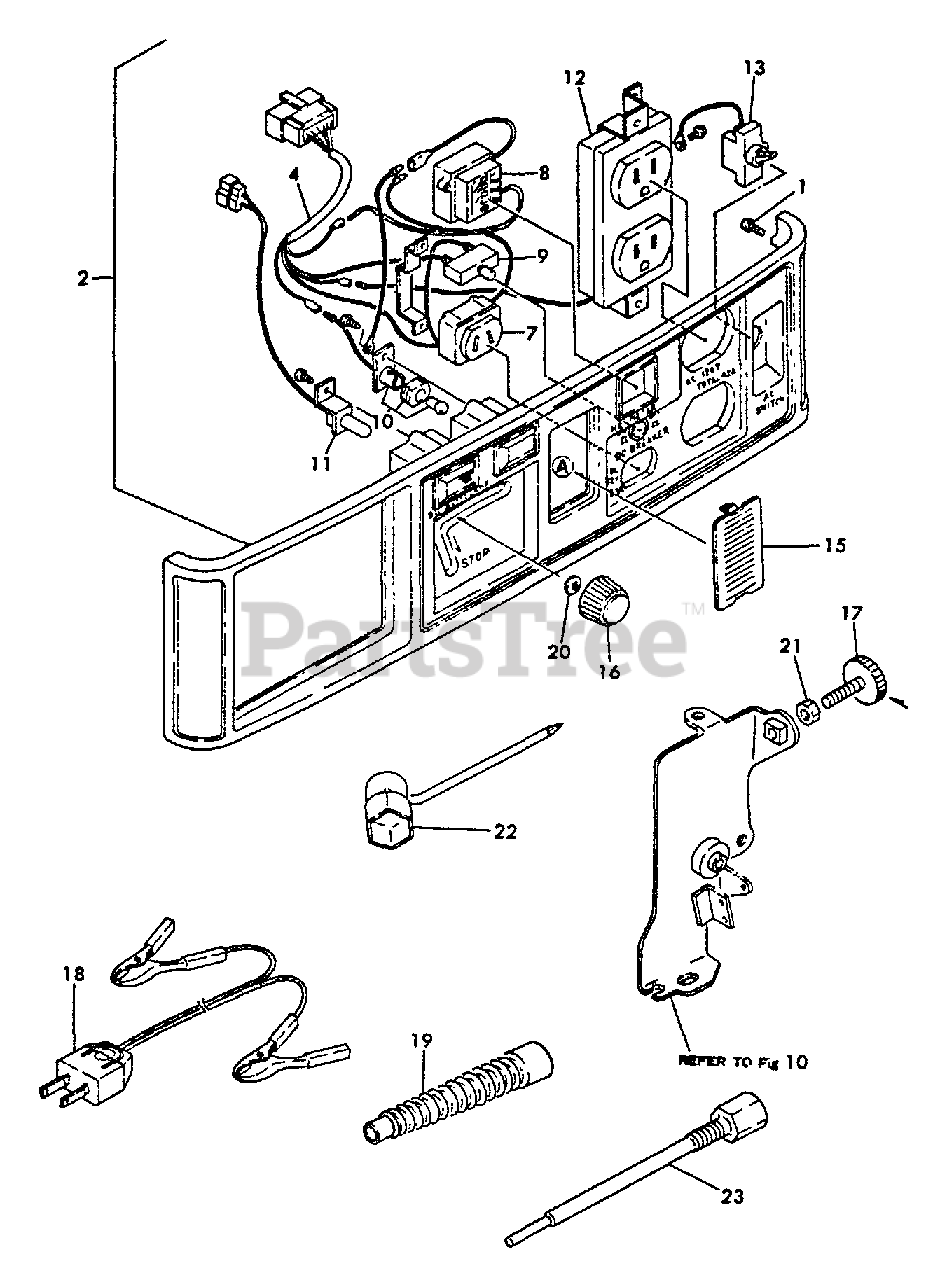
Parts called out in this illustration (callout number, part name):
1	SCREW - 4×8
2	PANEL BOARD ASSY
4	WIRE HARNESS
7	PLUG SOCKET 15A
8	FREQUENCY METER
9	DC PROTECTOR
10	LAMP, PILOT
11	LAMP, OIL ALERT
12	AC RECEPTACLE
13	AC BREAKER
15	BLIND COVER
16	KNOB
17	SCREW, ADJUST
19	OIL FUNNEL
21	LOCKNUT - 6 -- PLATED
22	BOX SPANNER
23	BOX SPANNER
